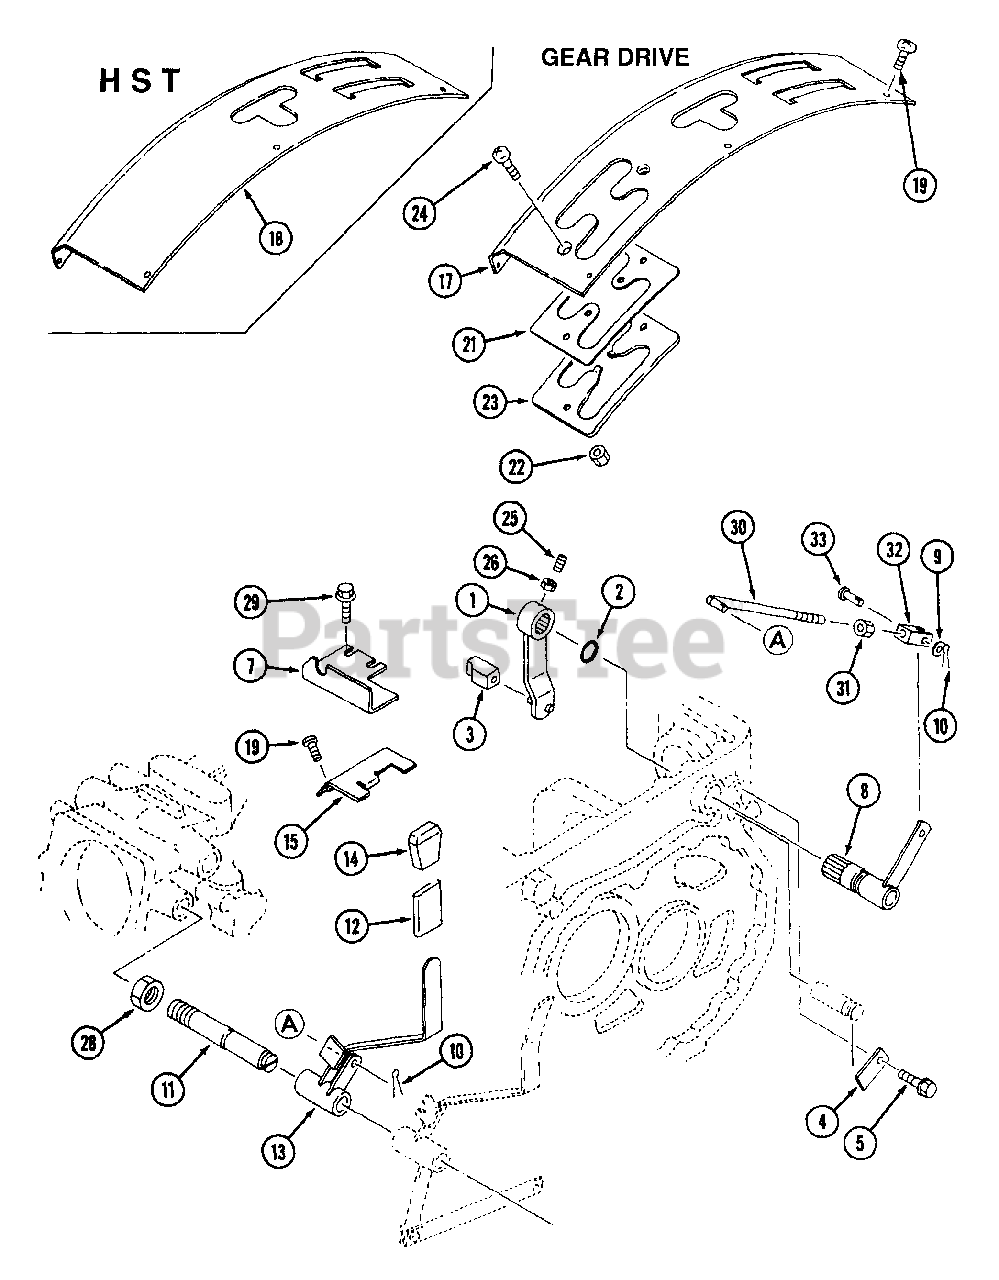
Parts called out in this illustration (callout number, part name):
1	Shifter, R. PTO
10	Pin, Split
11	Shaft, PTO Lever
13	Lever, R. PTO
17	Lever, Guide L.H. (Gear)
18	Lever, Guide L.H. (HST)
21	Guide, Rubber (Gear)
22	Nut (Gear)
23	Plate (Gear)
24	Screw (Gear)
